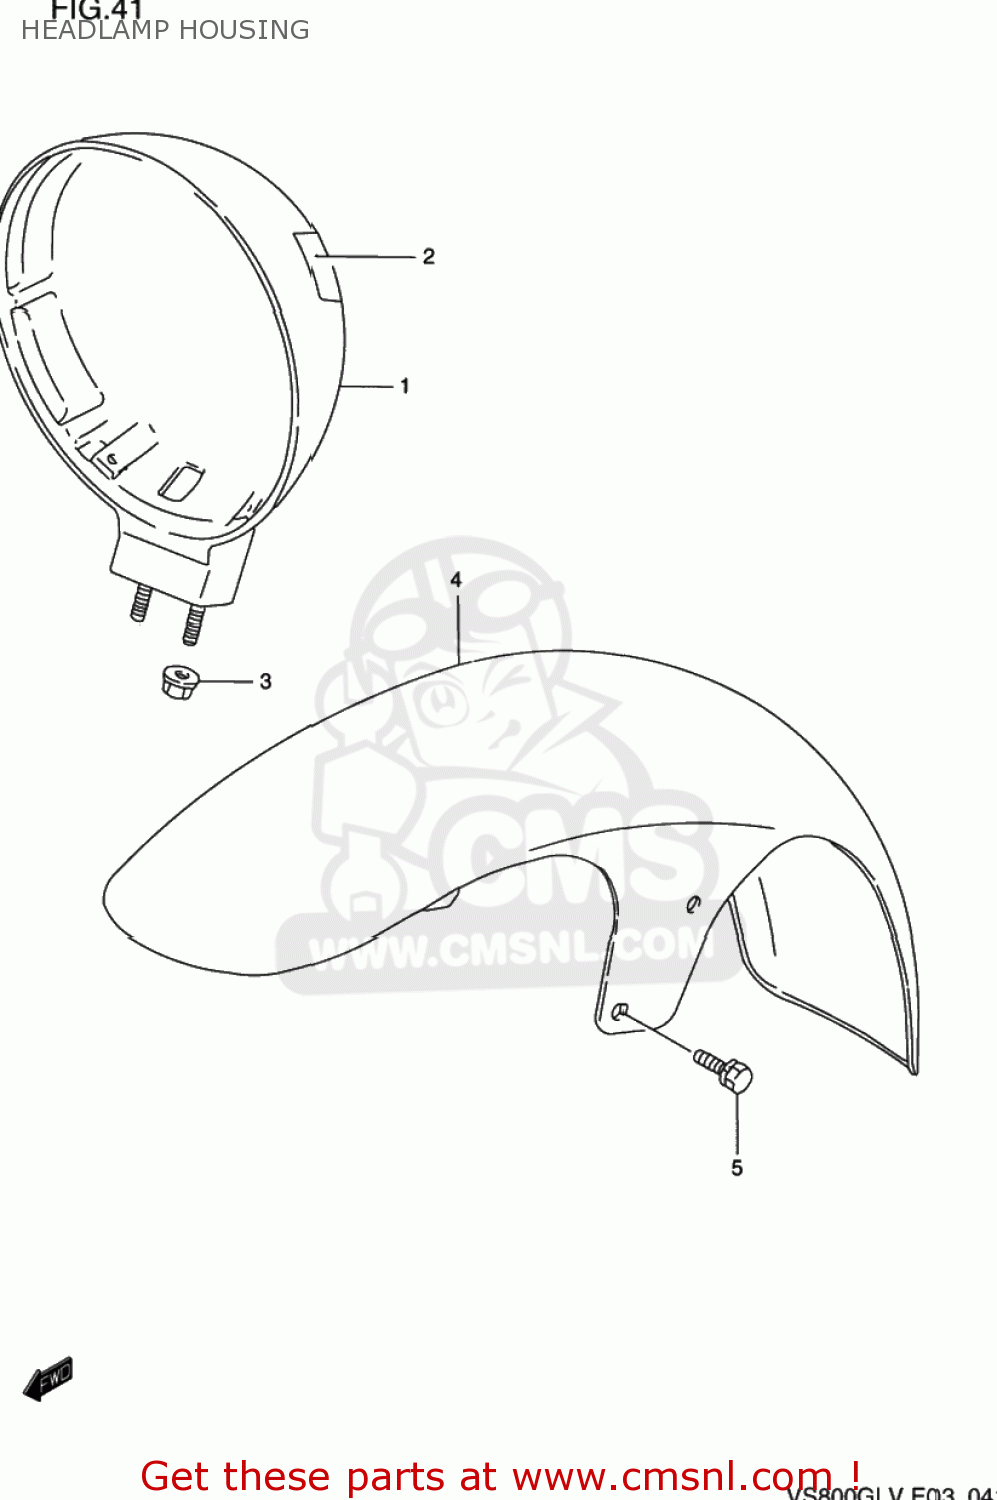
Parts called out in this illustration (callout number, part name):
1	HOUSING,HEADLAMP
2	TAPE,FRAME HEAD COVER
3	NUT
4	FENDER,FR
5	BOLT
